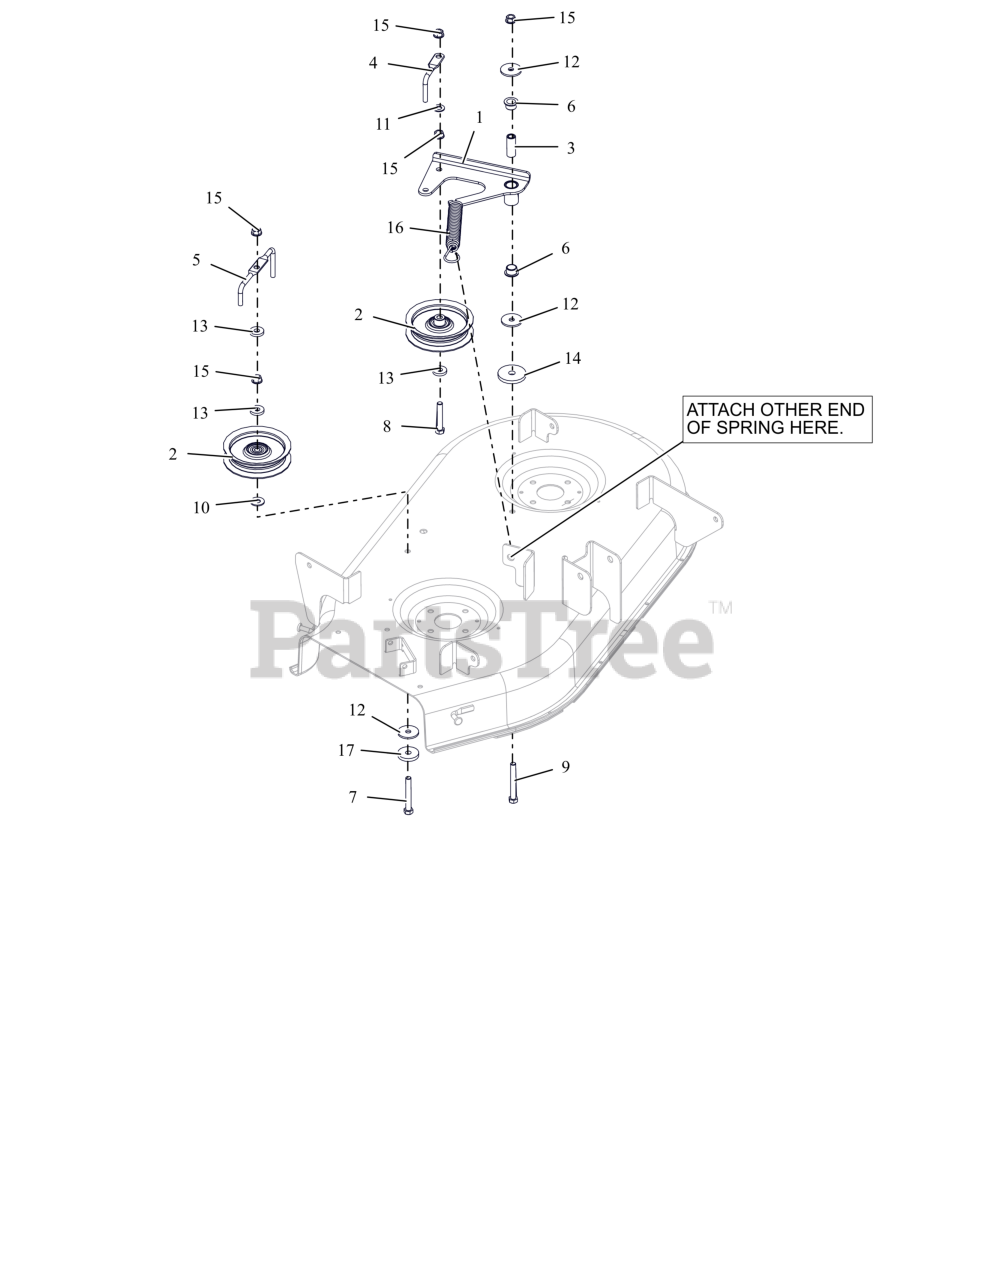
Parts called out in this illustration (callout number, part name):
1	WLDMT, IDLER ARM (ORANGE)
2	IDLER, FLAT - 4.06" X .75"
3	SPACER, .375IDX.625ODX1.66 PM
4	WIREFORM-BELT FINGER
5	BELT FINGER
6	BSHG-FLG, .625X.750X.500X1.00
7	BLT, HEX .38-16X2.75 G5 ZCC
8	BLT,HEX .38-16X2.25 G5 ZCC
9	BLT, HEX .38-16X3.00 G5 ZCC
10	WSHR,FLT .438X1.00X.083 ZCC
11	WSHR,FLT .406X.812X.065 ZCC
12	WSHR, FLT .380X1.50X.125 ZCC
13	WSHR, FLT .406X1.00X.188 ZCC
14	WSHR, FLT .469X2.00X.250 ZCC
15	NUT-LK-CTR-FLG .375-16 GF ZCC
16	SG-TENS .135X.98X6.0 WLD 62
17	WSHR, FLT .406X1.50X.245 ZCC
